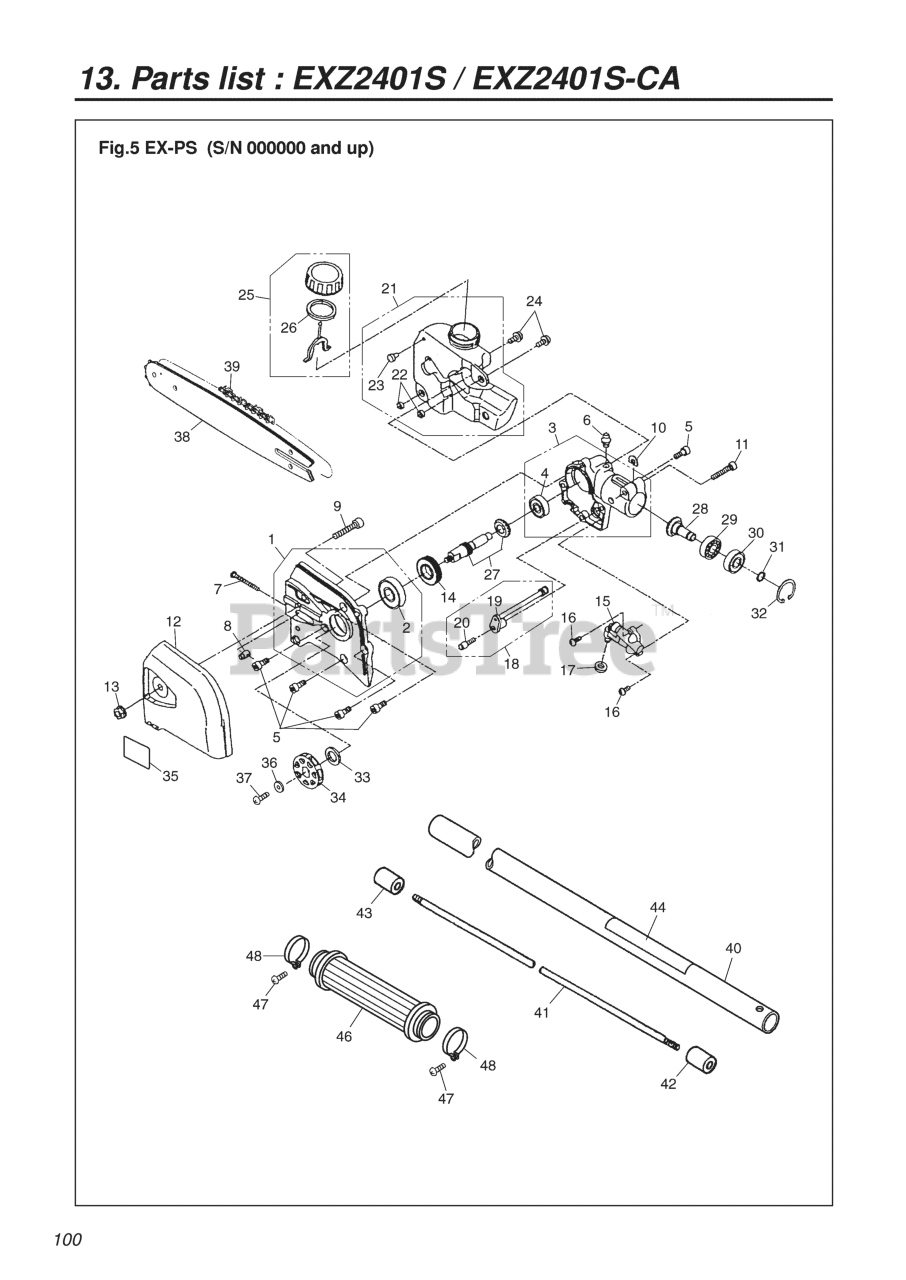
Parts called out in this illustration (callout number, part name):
2	BEARING
3	GEARCASE COMP (RIGHT)
5	BOLT, M5 x 12
6	FITTING, GREASE
7	SCREW
8	NUT
9	BOLT, M6 x 30
10	SHIM
12	COVER, CHAIN
13	NUT
14	GEAR, WORM
15	PUMP ASSY, OIL
16	SCREW, M4 x 10
17	GASKET
18	PIPE ASSY, OIL
19	PIPE, OIL
20	FILTER
21	TANK ASSY, OIL
22	COLLAR
23	VALVE
24	SCREW, M5 X 12
25	CAP ASSY, OIL
26	GASKET, OIL CAP
27	SHAFT, GEAR
28	GEAR, BEVEL
29	BEARING (RPLS T3403-13530)
31	RING, SNAP (RPLS T3300-13330)
32	RING, SNAP, M24 x 1.2
33	COLLAR
34	SPROCKET
35	LABEL (PSZ2500)
36	WASHER
37	SCREW
39	12
40	PIPE COMPLETE
41	SHAFT
42	JOINT, SHAFT (RPLS -12240)
43	SPACER
44	NAMEPLATE
46	GRIP
48	SCREW (RPLS 00260- )
